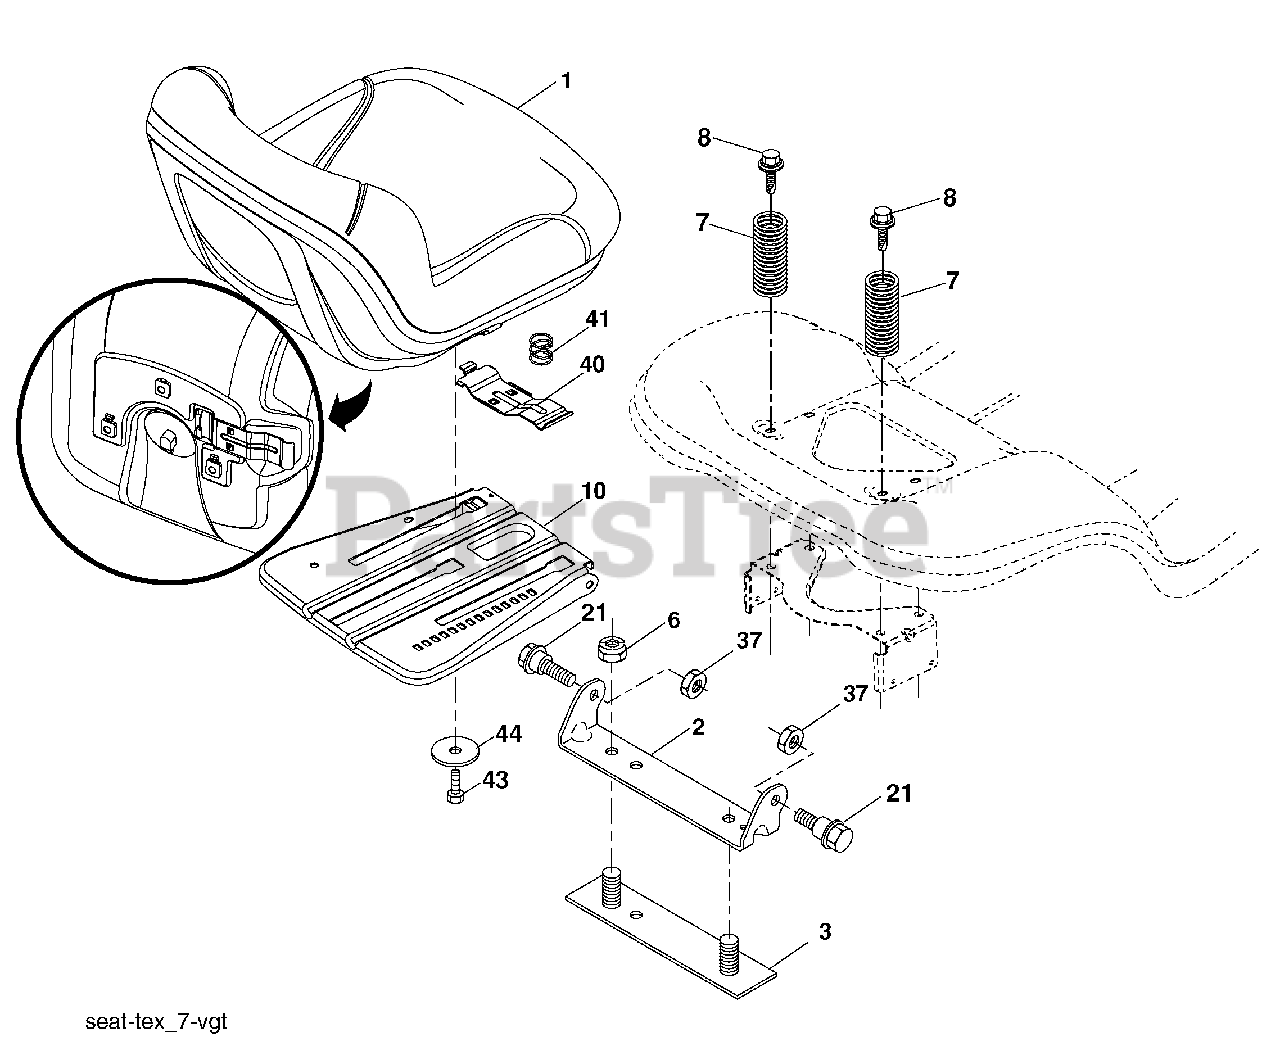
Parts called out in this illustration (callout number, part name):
1	Seat
2	Bracket Pivot Fender
3	Strap, Asm Fender
6	Nut, Lock W/Ins. 3/8-16 unc
7	Spring, Seat Cprsn
8	Bolt 5/16-18 uncx 3/4 w/Sems
10	Pan, Seat
21	Bolt, Shoulder 5/16-18
37	Nut, Lock 5/16-18 unc
40	Handle Slide
41	Spring Latch
43	Bolt 3/8-16 unc x 3/4
44	Washer 13/32 x 2 3/8 x 12 Ga.
